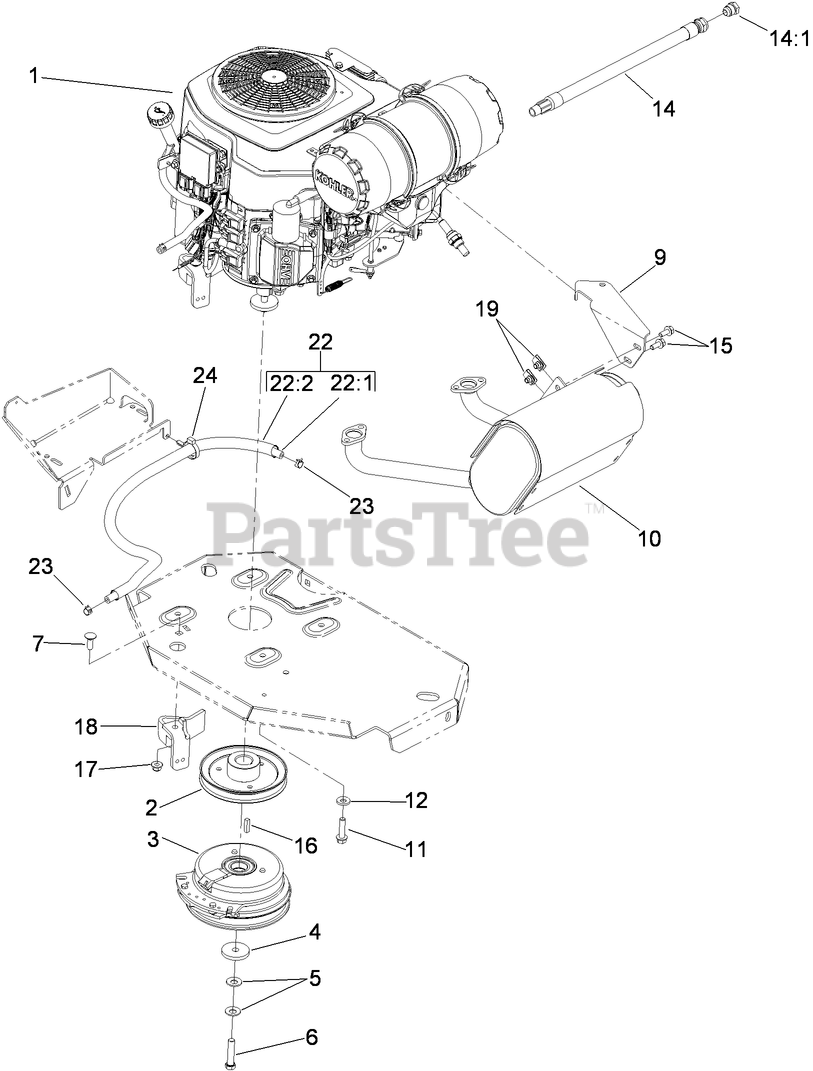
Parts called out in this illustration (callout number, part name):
2	SHEAVE
3	CLUTCH KIT
4	WASHER-CLUTCH
5	WASHER-SPRING
6	SCREW-HH W/LOCTITE
7	SCREW-CARR
9	BRACKET-MUFFLER
10	MUFFLER
11	SCREW-HWH
12	WASHER-BELLEVILLE
14	OIL DRAIN HOSE ASM
15	SCREW-HHF
17	NUT-HF, NI
18	CLUTCH-ANCHOR
19	NUT-U
22	FUEL LINE ASM
22:1	HOSE-FUEL
22:2	SLEEVE-THERMAL
23	CLAMP-HOSE
24	CLAMP-HOSE
